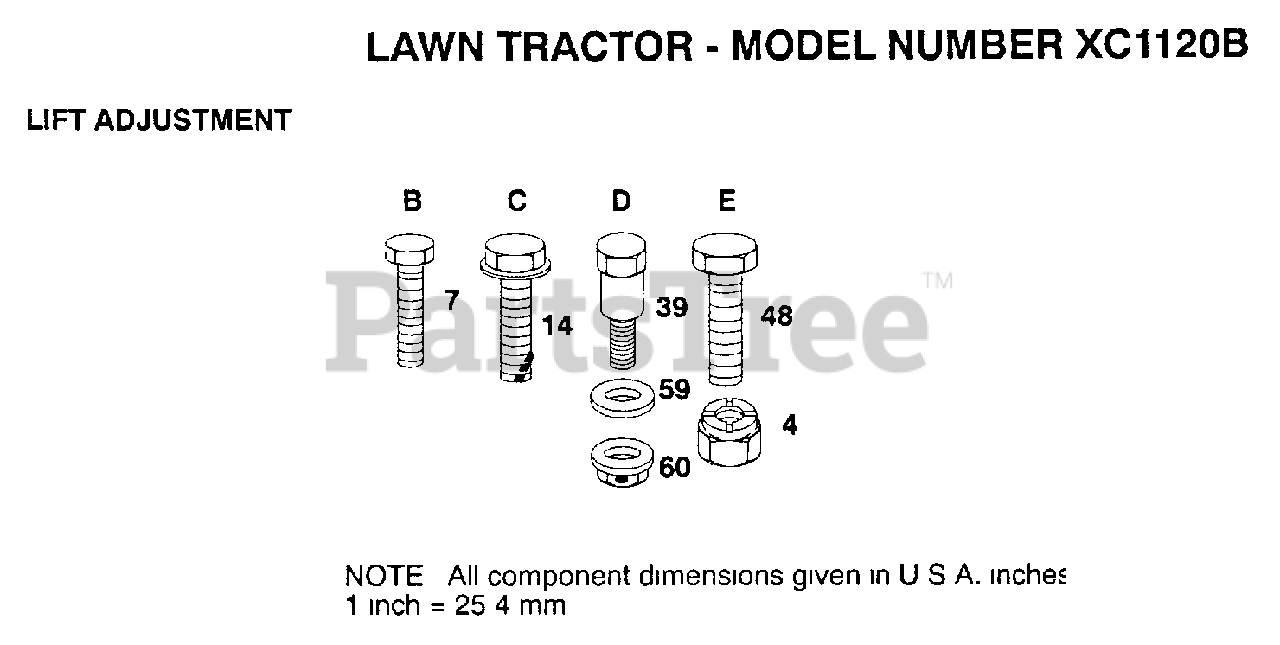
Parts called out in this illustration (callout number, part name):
7	SCREW
14	SCREW
39	"BOLT, SHOULDER LT"
59	WASHER T
60	NUT SPECIAL T
